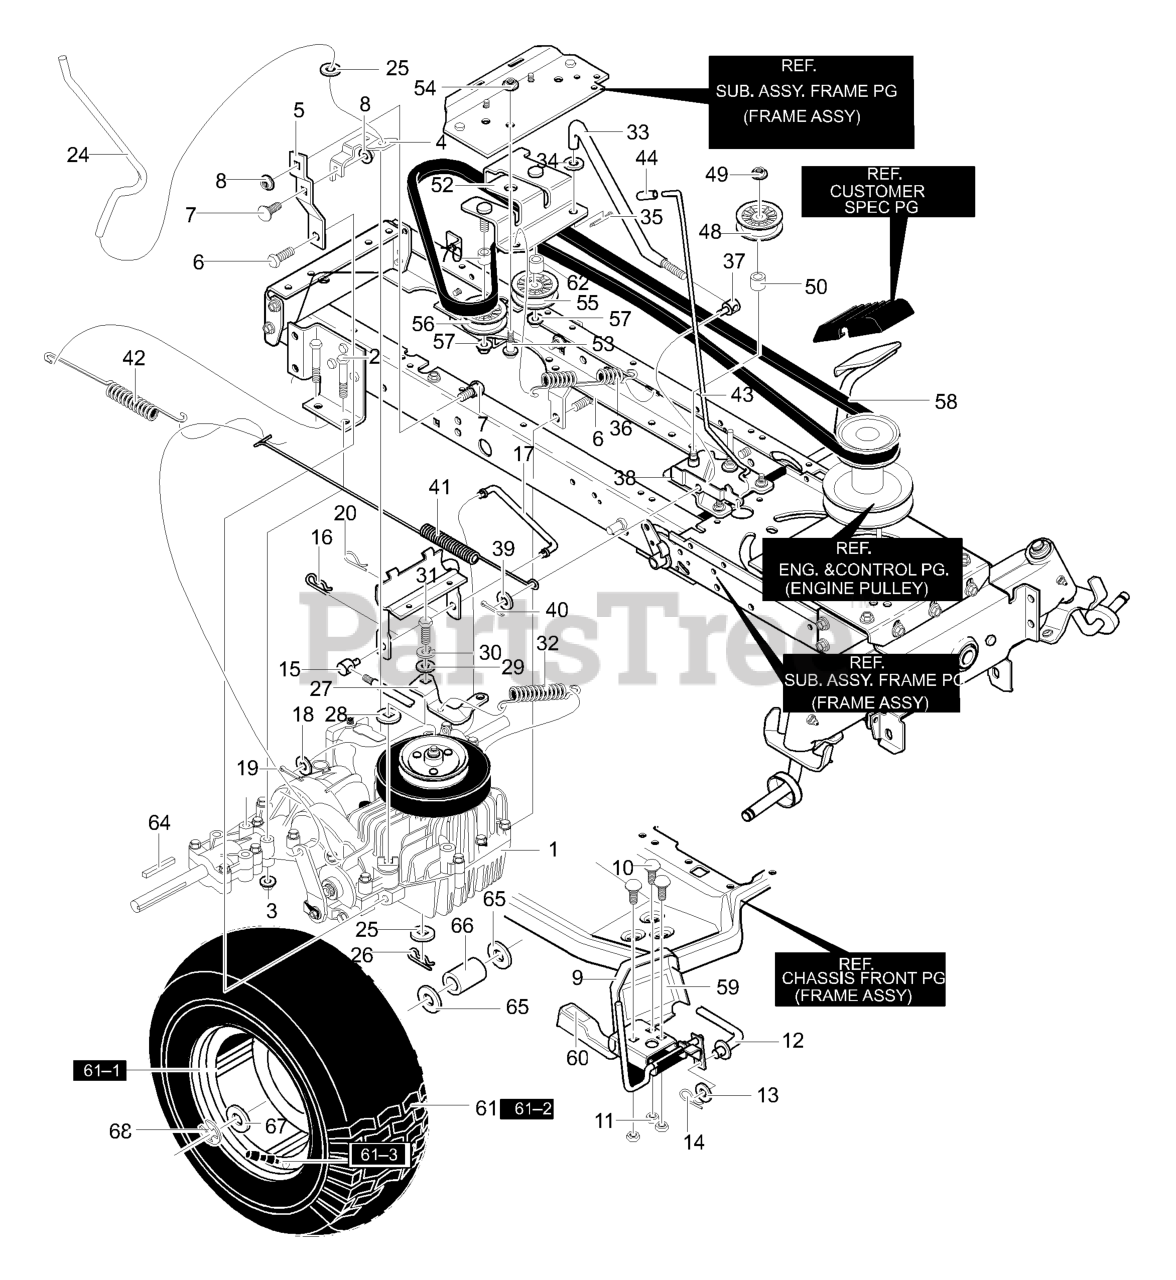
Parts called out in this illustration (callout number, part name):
1	Transaxle, VST205 **
2	Screw, 5/16-18 x 2.50
3	Nut, 5/16-18 Wdfllk
4	Bracket, Disconnect
5	Torque Strap
6	Screw, 5/16-18 x 0.75
7	Bolt, 5/16-18x.63
8	Nut, 5/16-18 Hexwdfllk Wh
9	Pedal Assy., Hydro
10	Bolt, 5/16-18x.75
11	Nut, 5/16-18
12	Rod, Pedal Link
13	Washer
14	Hair Pin
15	Adjust Nut 1/2-13
16	Hair Pin
17	Rod Hydro Link
18	Flat washer
19	Cotter Pin
20	Hair Pin
24	Rod, Disconnect
25	Washer, Flat
26	Pin, Cotter
27	Arm Disconnect
29	Flat washer
30	Washer
31	Screw, 1/4-28x.75
32	Spring, Extension
33	Rod, Clutch
34	Flat washer
35	Cotter Pin
36	Spring, Clutch
37	Nut, Adjusting
38	Latch, Park Brake
39	Flat washer
40	Cotter Pin
41	Spring, Extension
42	Spring, Tension
43	Park Brake Rod
44	Grip
48	Pulley, Idler
49	Nut, 3/8-16
50	Spacer, 1/2 to 17MM
52	Asm., Bracket Idler
53	Bolt, 3/8-16
54	Nut, 3/8-16
55	Pulley, Idler
56	Pulley, Idler
57	Nut, 3/8-16
58	Belt, Motion Drive
60	Pad, Toe Sandpaper
61	Tire & Rim
61-1	Valve Stem
62	Spacer 1/2 to 17MM
64	Key, Square
65	Flat washer
66	Spacer .87x1.78
67	Flat washer
68	Ring, E
70	Spacer 1/2 to 17MM
